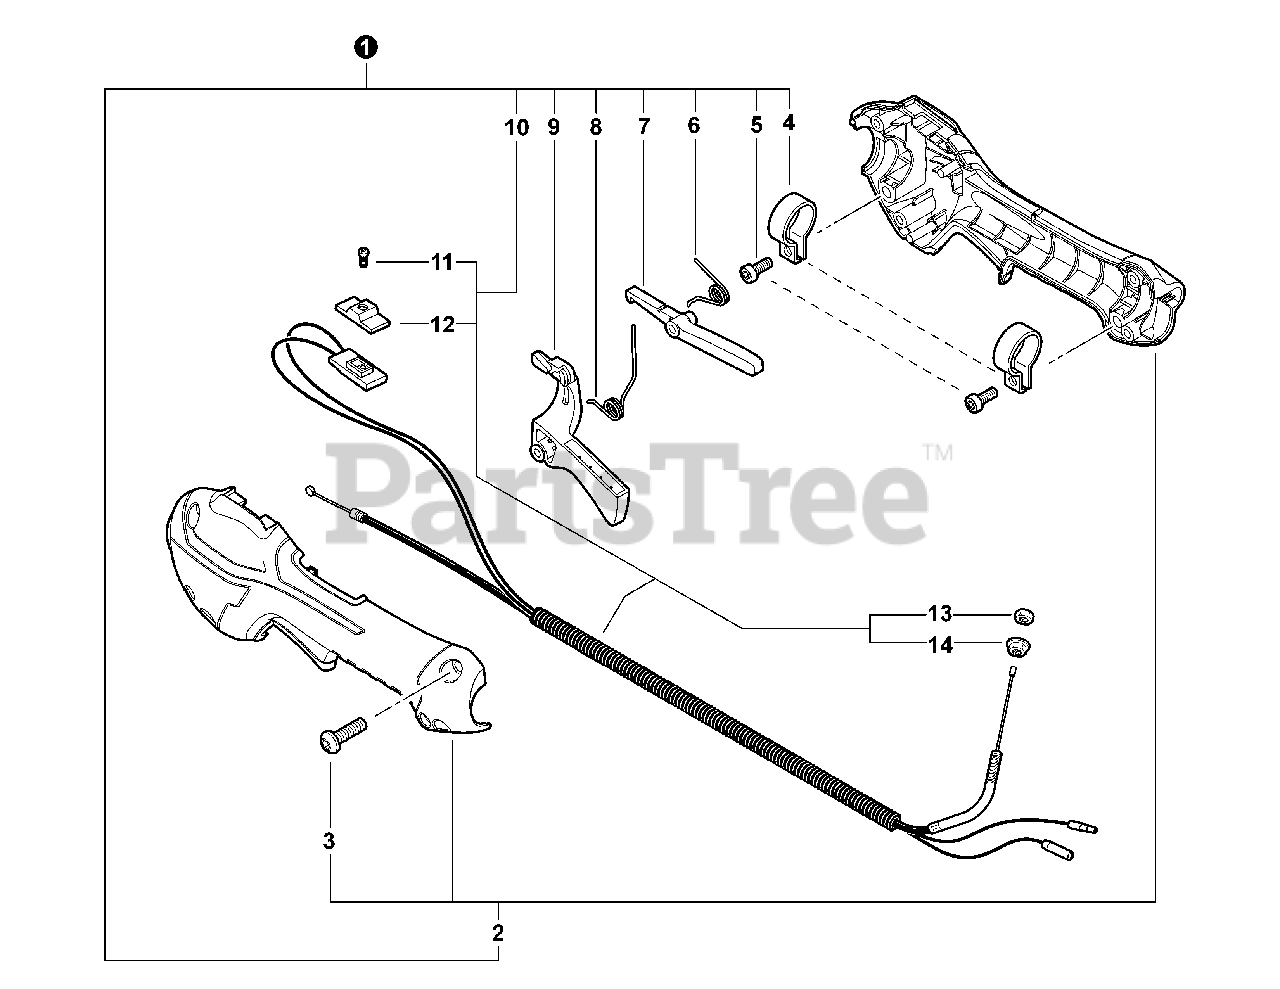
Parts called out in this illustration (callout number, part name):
1	CONTROL HANDLE KIT
2	CONTROL HANDLE KIT
3	BOLT, TORX 5×16
5	BOLT, TORX 5×16
6	SPRING, TORSION
7	LEVER, THROTTLE LOCKOUT
8	SPRING, TORSION
9	TRIGGER, THROTTLE
10	CABLE ASSY, CONTROL
11	SCREW 3×10
12	KNOB, SWITCH - ORANGE
14	NUT, FLANGE M6
